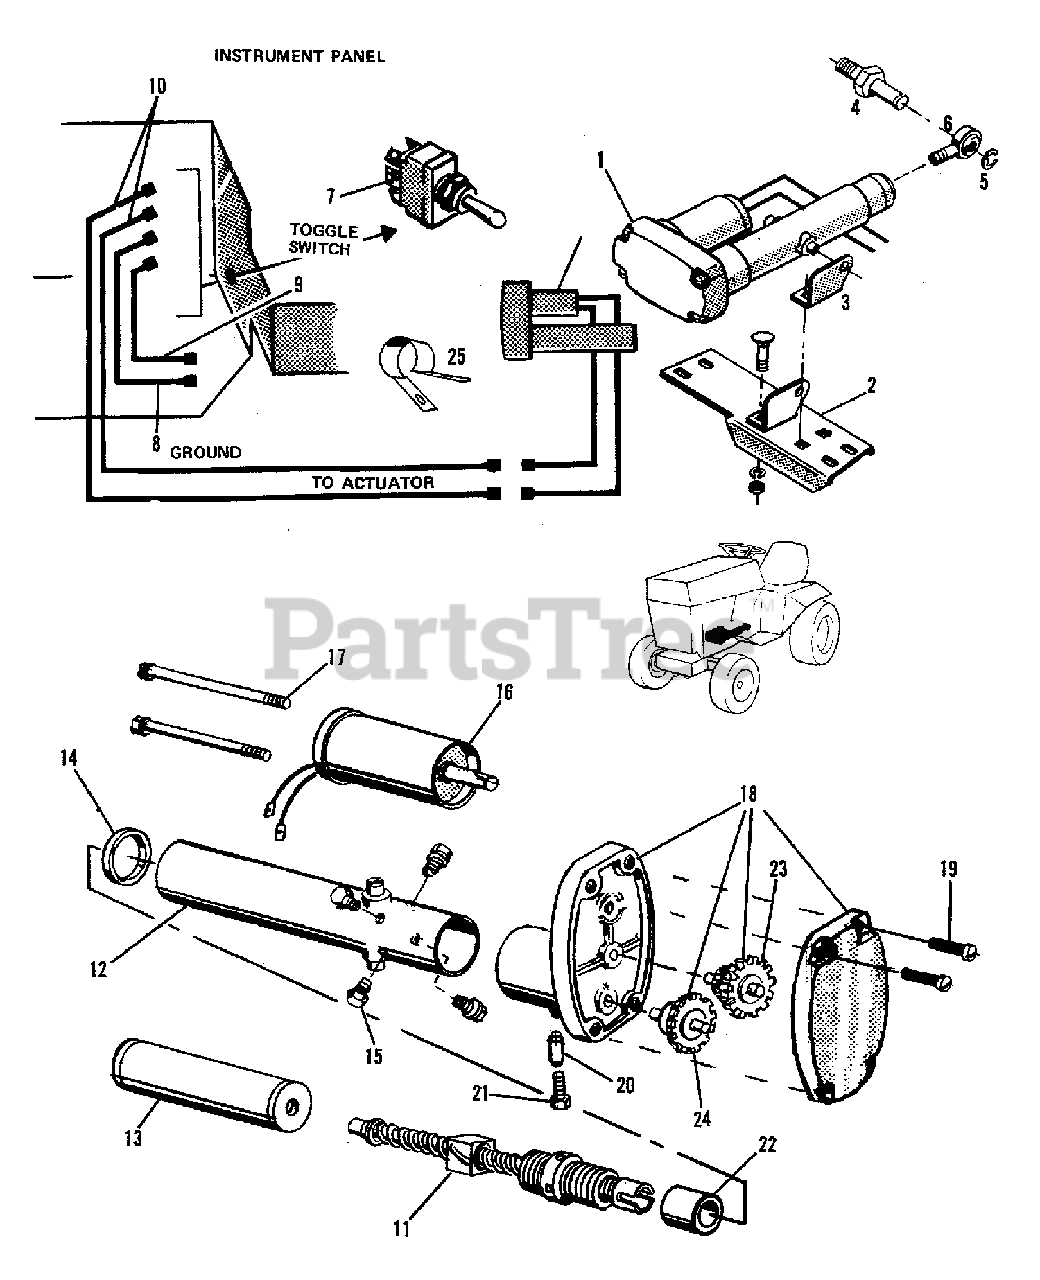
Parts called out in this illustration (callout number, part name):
1	ACTUATOR, Electric
2	SUPPORT, Actuator
2	CAPSCREW, 3/8NC x 1
2	WASHER, 13/32 x 7/8 x 14 GA
2	LOCKWASHER, 3/8
2	NUT, 3/8NC
3	BRACKET, Support
3	BOLT, 3/8NC x 1, Carriage
3	LOCKWASHER, 3/8
3	NUT, 3/8NC
4	PIN, Pivot
4	LOCKWASHER, 1/2
4	NUT, 1/2NC
4	WASHER, 17/32 x 1-1/4 x 16 Ga.
5	RING, External 1/2" Shaft "E"
6	NUT, 1/2NF-Jam
7	SWITCH, Toggle
8	LEAD, Switch Connector & Ground
9	LEAD, Lift Switch To PTO Switch
10	HARNESS, Switch to Actuator
11	SCREW & BRAKE ASSEMBLY, Ball Bearing
12	TUBE ASSEMBLY, Outer
13	TUBE ASSEMBLY, Inner
14	SEAL, Quadrant Ring
15	SCREW, Thread Cutting
17	SCREW, Motor
18	GEAR BOX ASSEMBLY
19	SCREW, Filister Head, #10-32 Thread
21	SCREW, Thread Forming
22	SLEEVE, Coupling
23	GEAR ASSEMBLY
24	GEAR ASSEMBLY
25	CLIP, Closed, 3/8
25	CAPSCREW, 3/8NC x 1-1/2
25	LOCKWASHER, 3/8
25	NUT, 3/8NC
